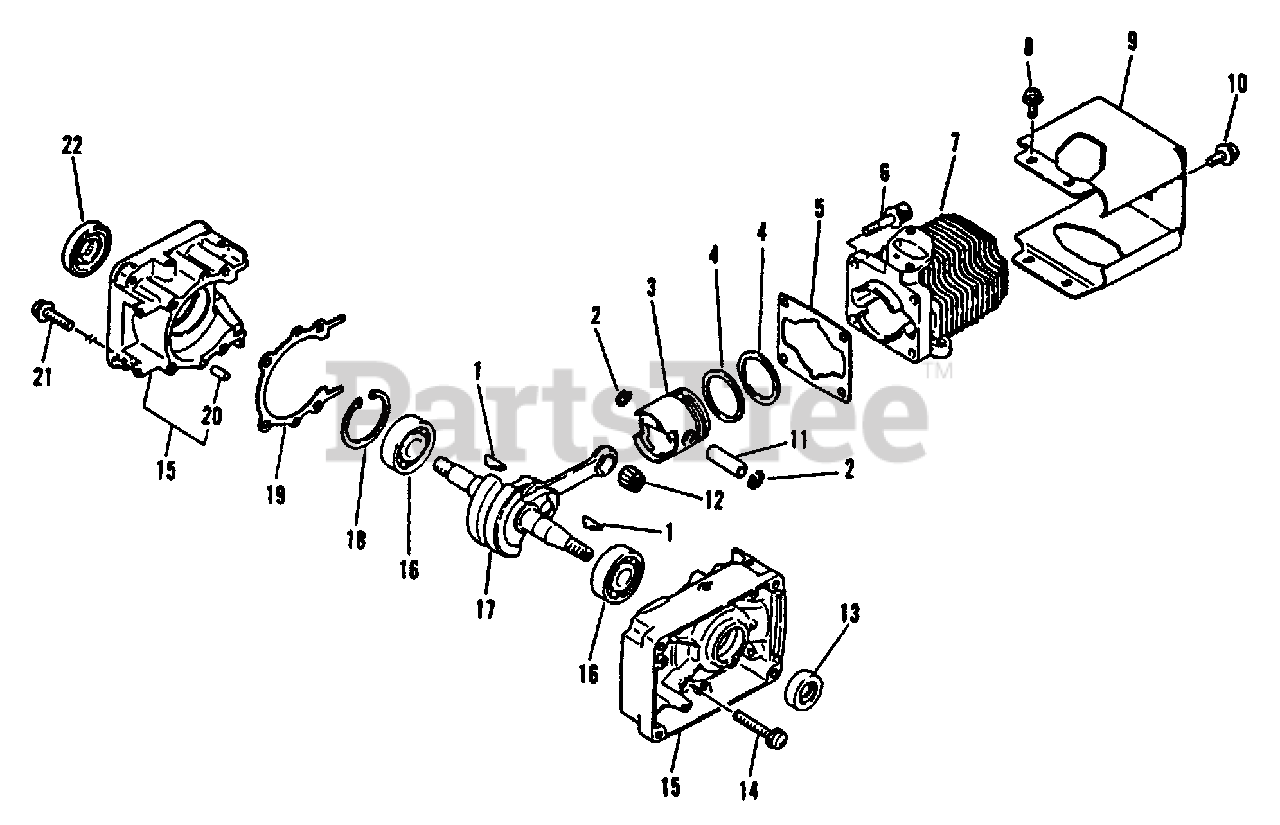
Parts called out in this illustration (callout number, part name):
1	KEY - 3X14
2	RING, RETAINING
3	PISTON
4	RING, PISTON
5	GASKET, CYLINDER
6	SCREW - 5X20
7	CYLINDER
8	SCREW - 4X10
9	SHIELD, CYLINDER
10	SCREW - 5X10
11	PIN, PISTON
12	BEARING, NEEDLE
13	SEAL, OIL
14	SCREW - 5X30
15	CRANKCASE KIT
16	BEARING, BALL - 6201
17	CRANKSHAFT ASSY
18	RING, RETAINING - 32
19	GASKET, CRANKCASE
20	PIN - LOCATING
21	SCREW - 5X20
22	SEAL, OIL
22	GASKET KIT
